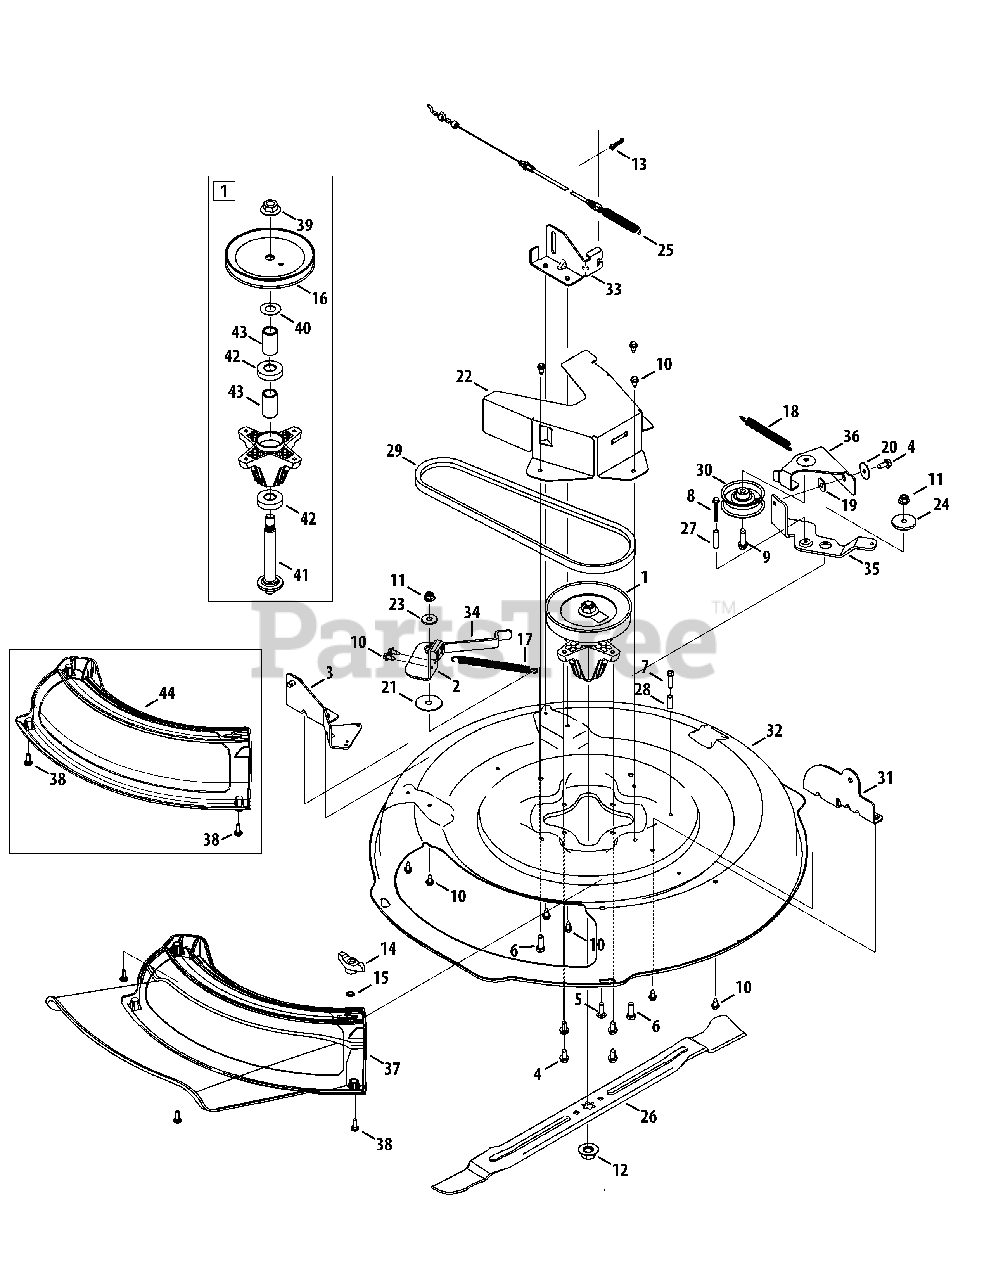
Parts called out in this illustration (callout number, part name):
1	Spindle Pulley Assembly, 6.3 DIA
2	PTO Brake Assembly Bracket
3	Rear Deck Assembly Bracket
4	Tap Screw, 5/16-18, .750
5	Carriage Screw, 5/16-18, 1.00
6	Hex Head Screw, 3/8-16, 1.00
7	Tap Screw, 1/4-20, 1.500
8	Tap Screw, 1/4-20, 1.750
9	Tap Screw, 3/8-16, 1.250
10	Tap Screw, 1/4-20 X .625
11	Flange Lock Nut, 3/8-16
12	Flange Nut, 5/8-18
13	Bow-Tie Cotter Pin, 72
14	Wing Knob, 5/16-18
15	Speed Nut, .3125 ID
16	Deck Pulley, 6.3 DIA
17	Ext. Spring, .708 X 7.357 X .094
18	Ext. Spring, .565 OD X 5.00 LG
19	Shoulder Bushing, .320 ID X .135
20	Flat Washer, .330x1.250x.060
21	Thrust Washer, .445X.1.920X.060
22	Deck Belt Cover
23	Shoulder Spacer, .625 ID X .169
24	Shoulder Spacer, .8840 X .190
25	PTO Cable
26	Cutting Blade, 30.00" 3-IN-1
27	Spacer, .260 X .372 X 1.420 LG
28	Spacer, .260 x .375 x 1.030 LG
29	V-Type Belt, 5L, 45.15 LG
30	Flat Idler Pulley, 2.75 OD
31	Front Deck Bracket
32	Deck, 30" w/out Nozzle
33	RR Deck Bracket, LH
34	Release Brake Bracket
35	Lower Floating Idler Bracket
36	Upper Floating Idler Bracket
37	Chute Deflector
38	Shoulder Screw, 1/4-15 x .750
39	Flange Nut, 5/8-18
40	Shim Washer, .760X1.500X.030
41	Spindle Shaft, 6.11 LG.
42	Ball Bearing, .787ID X 1.85 ODX.551
43	Spacer, .792 X 1.060 X 1.860 LG
44	Mulch Plug
